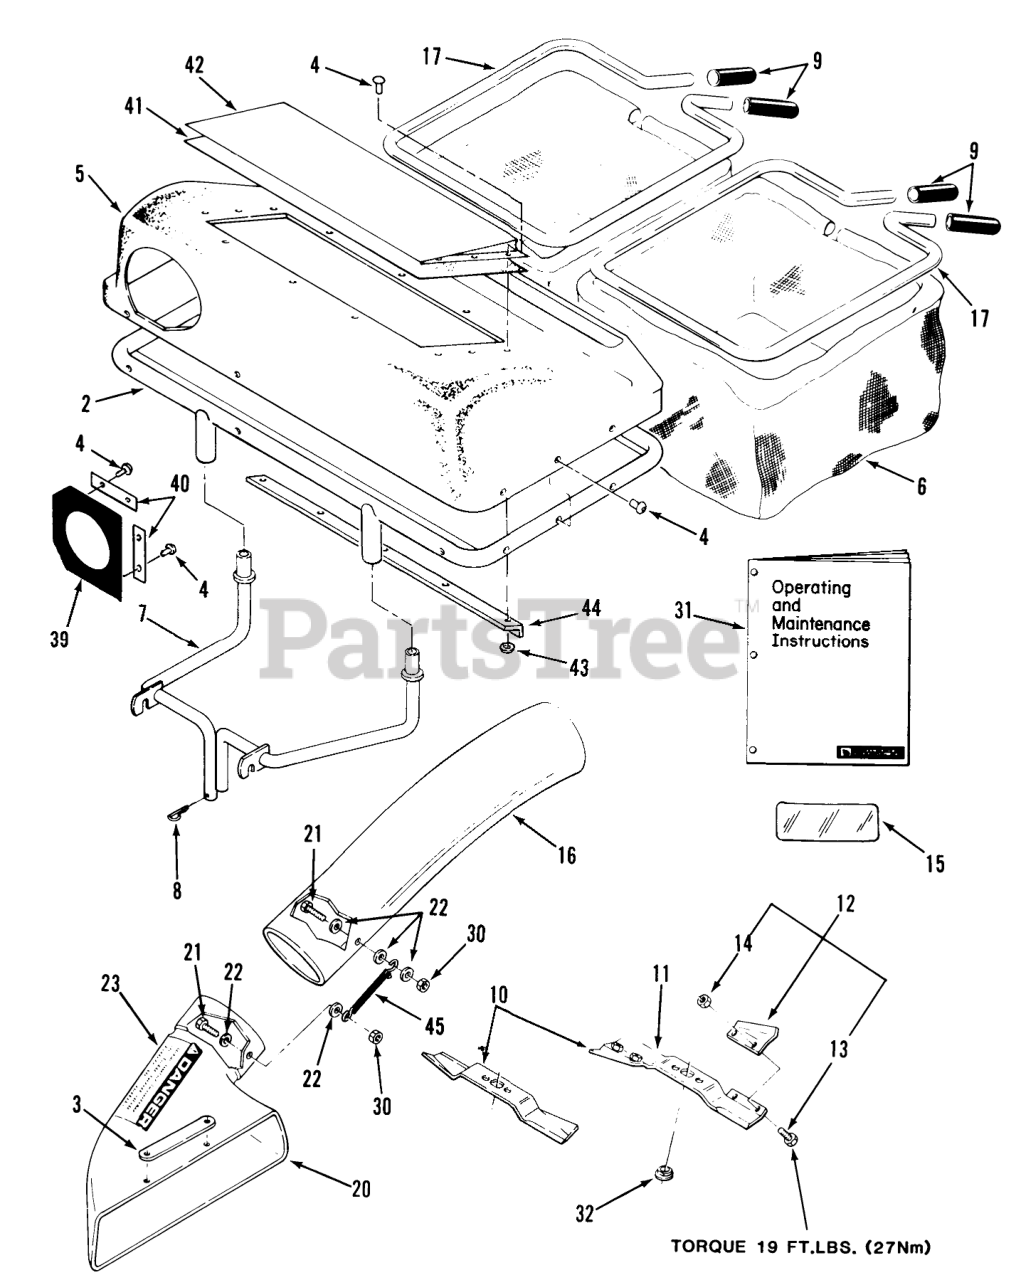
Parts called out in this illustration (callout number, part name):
2	Frame
3	PLATE-ELBOW B
4	RIVET-BLIND
5	TOP-BAG'R (37")
6	BAG-BLACK(37"TWIN)
7	ASY-QUICK ATTACH B
8	Hairpin
9	GRIP
10	Blade Kit (includes LH blade, RH blade with tabs, hardware and spacer)
11	High Lift Blade (includes item 12) RH
12	Lift Tab Kit (includes items 13 & 14)
13	BOLT 5/16-18X5/8
14	NUT-LOCK 5/16-18
15	DECAL-OVERLAY
16	Tube (includes items 21, 22 & 30)
17	FRAME BAG B
20	Elbow (includes items 21, 22, 23 & 30)
21	Bolt
23	DECAL-DANGER
30	Nut
31	Operating and Maintenance Instructions
32	SPACER BLADE
39	SEAL-CHUTE
40	STRAP-SEAL
41	Top Screen
42	Screen Cover
43	Washer
44	Top Stiffener
45	STRAP
